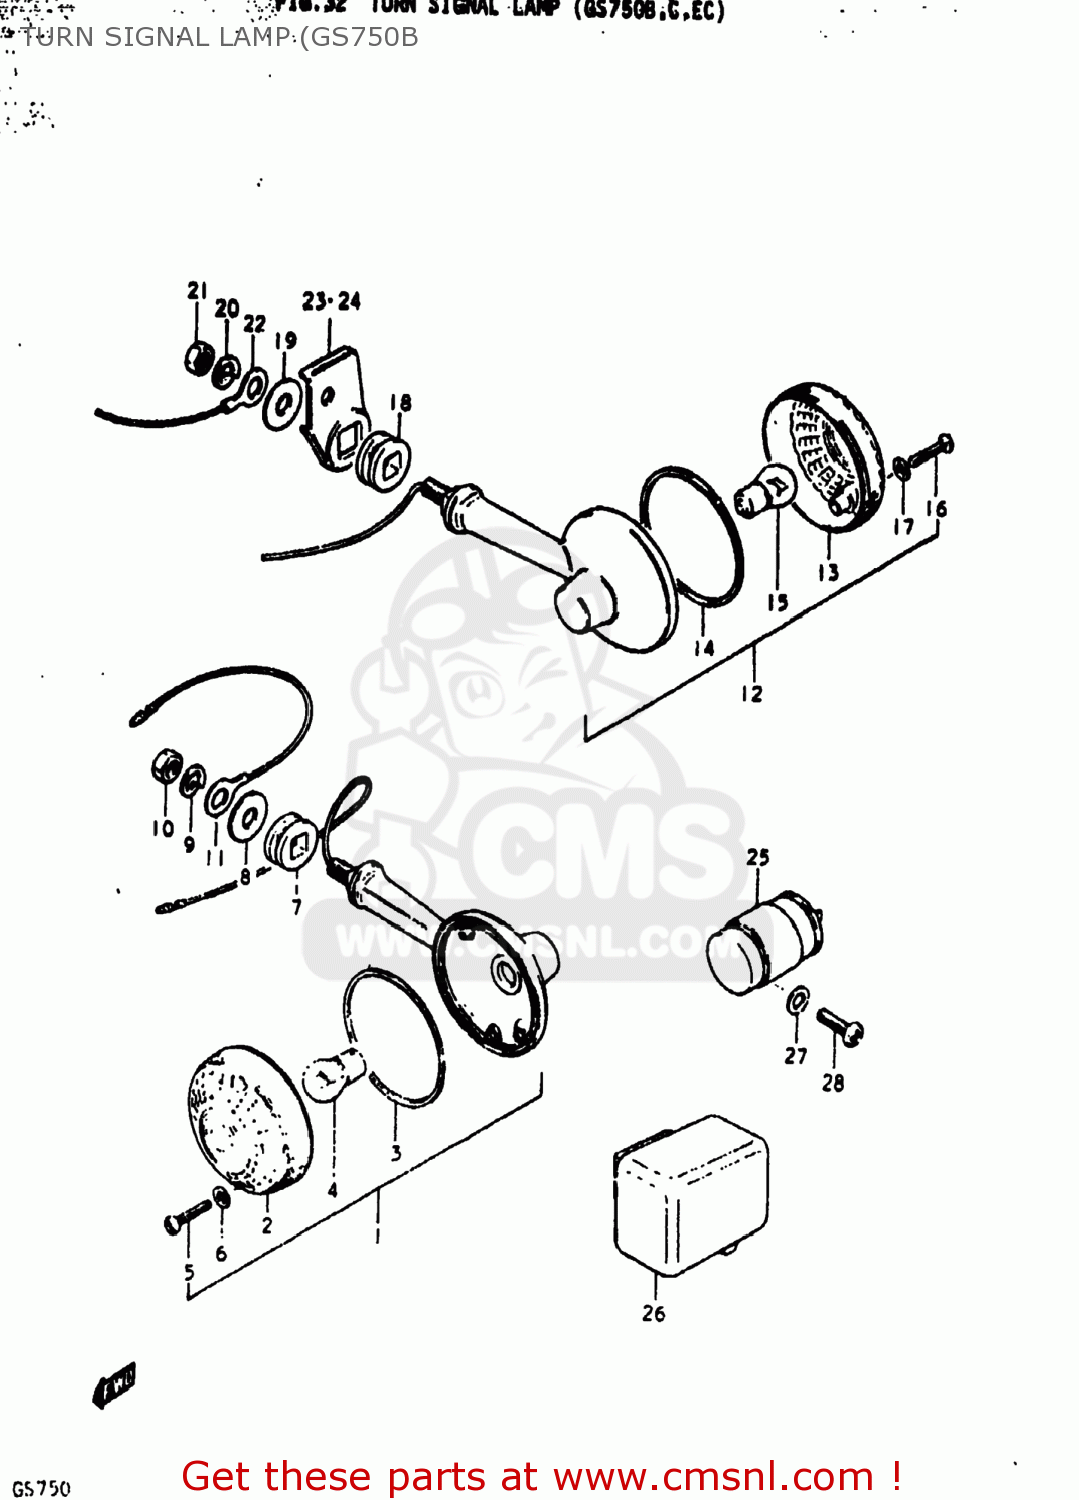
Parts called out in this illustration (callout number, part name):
1	LAMP ASSEMBLY,FRONT TURN SIGNAL
2	LENS
3	GASKET (NAS)
4	BULB(12V23W,STANLEY,A4577A)
5	SCREW
6	GASKET (NAS)
7	CUSHION
8	WASHER (10.5X30X2.3)
9	LOCK WASHER
10	NUT
11	WIRE
12	LAMP ASSEMBLY,FRONT TURN SIGNAL
13	LENS
14	GASKET (NAS)
15	BULB(12V23W,STANLEY,A4577A)
16	SCREW
17	GASKET (NAS)
18	CUSHION
19	WASHER (10.5X30X2.3)
20	LOCK WASHER
21	NUT
22	WIRE
23	BRACKET,RR TURNSIGNAL LAMP,R
24	BRACKET,RR TURNSIGNAL LAMP,L
25	RELAY,TURN SIGNAL
26	RELAY,TURN SIGNAL
27	WASHER
28	SCREW
